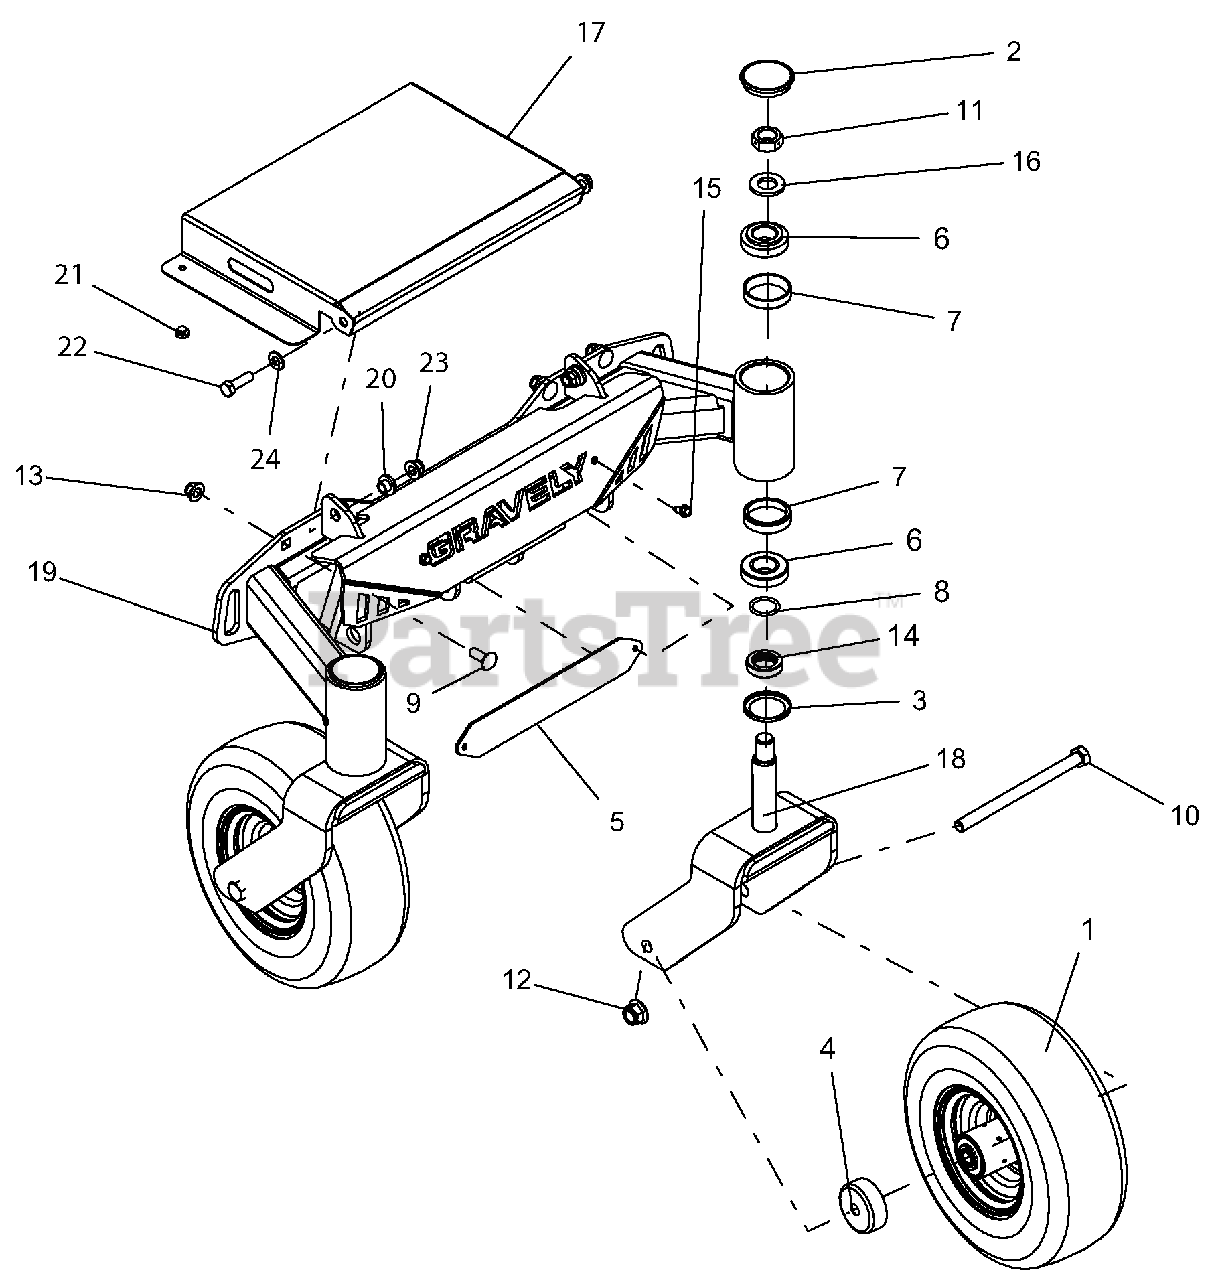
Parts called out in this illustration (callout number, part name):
1	ASM, WHEEL & TIRE 11 x 4.00 - 5
2	CAP, DUST
3	BEARING SEAL 1.5 X 2.0 X .18
4	SHIELD, WHEEL BEARING
5	BACK, NAMEPLATE
6	BRG, CONE W/ GREASE
7	BRG, CUP 1.980X.420
8	O-RING 1.000 X 1.250
9	BLT-RDHDSQNK .38-16X1.00 G5 YWZC
10	BLT-HEX .50-13X7.00 GR5 YWZC
11	@NUT-LK-CTR-JAM .75-16 YWZC
12	NUT-LK-NYL-FLG .50-13 YWZC
13	NUT-LK-NYL-FLG .38-16 YWZC
14	SPCR, CASTER FORK (1.00)
15	SCR-TAP .25-20X.50 HWH TR YWZ
16	WSHR-FL-STL.812X1.50X.135YWZC
17	SHIELD, FRONT
18	WLDMT, CASTER FORK
19	WLDMT, FRONT AXLE
20	BSHG, FLG .385 X .500 X .875 X .406
21	BUMPER GROMMET .125 X .25 REV
22	BLT-HEX .38-16X1.25 GR5 YWZC
23	NUT-LK-NYL-FLG .38-16 YWZC
24	WSHR-FL-STL.406X.812X.065 YWZ
